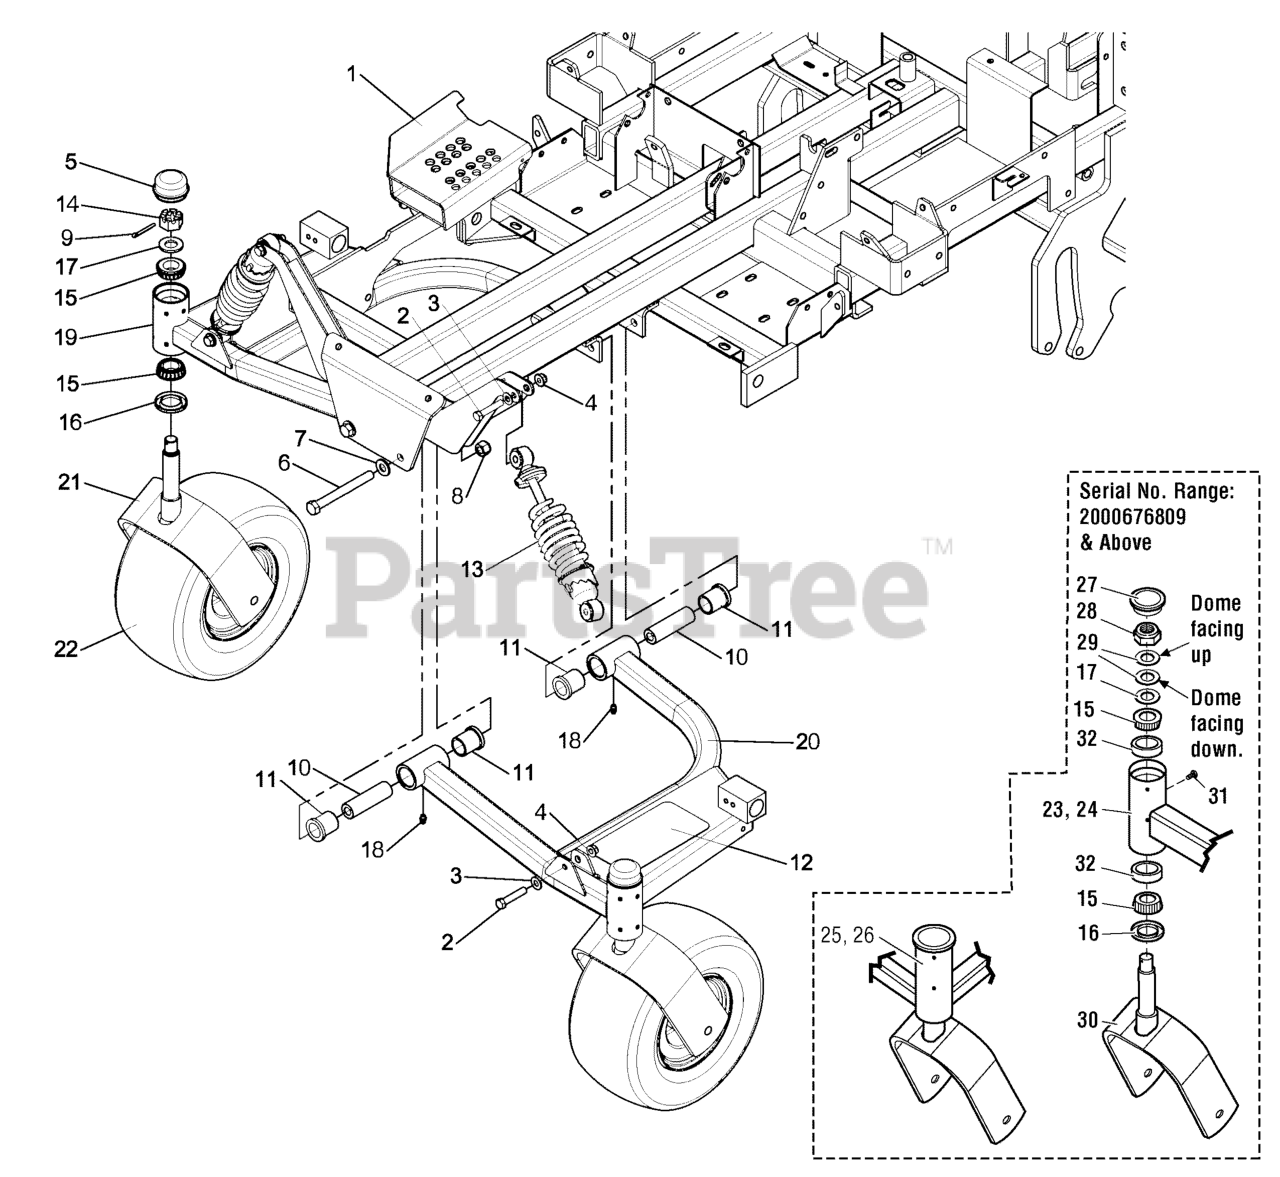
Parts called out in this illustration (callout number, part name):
1	WELD, MAIN FRAME IS4500
2	BOLT, 3/8-16 X 2, GD5, CZ
3	WASHER, 3/8 SAE
4	NUT, 3/8-16 HEX NYLOCK FLANGE
5	CAP, DUST
6	BOLT, 1/2-13 X 5" GD5 YZ
7	WASHER, 1/2 SAE
8	NUT, 1/2-13 HEX NYLON LOCK
9	PIN, COTTER, 1/8 X 1-1/4
10	SPACER, .52 X 1.00 X 3.50
11	BUSHING, FLANGE
12	SAFETY WALK, 4.00 X 7.50
13	SHOCK, FRONT, IS4500
14	NUT, 3/4-16 HEX SLOTTED
15	BEARING, TAPERED ROLLER, 1"
16	SEAL, GREASE
17	WASHER, 3/4 SAE
18	GREASE FITTING, 1/4-28 STRAIGHT
19	WELD, CONTROL ARM, RH - 61" MODELS
19	WELD, CONTROL ARM, RH - 72" MODELS
20	WELD, CONTROL ARM, LH - 61" MODELS
20	WELD, CONTROL ARM, LH - 72" MODELS
21	WELD, CASTER YOKE
22	TIRE ASSEMBLY
23	WELD, CONTROL ARM - RH - RED (61" MODELS)
24	WELD, CONTROL ARM - RH - RED (72" MODELS)
25	WELD, CONTROL ARM - LH - RED (61" MODELS)
26	WELD, CONTROL ARM - LH - RED (72" MODELS)
27	CAP, GREASE, LOW PROFILE
28	NUT, 3/4-16 HEX JAM NYLON LOCK
29	BELLEVILLE WASHER 1.500 X .755
30	WELD, CASTER YOKE - RED
31	BOLT, 1/4-28 X 1/2, GD5 YZ
32	BEARING CUP
